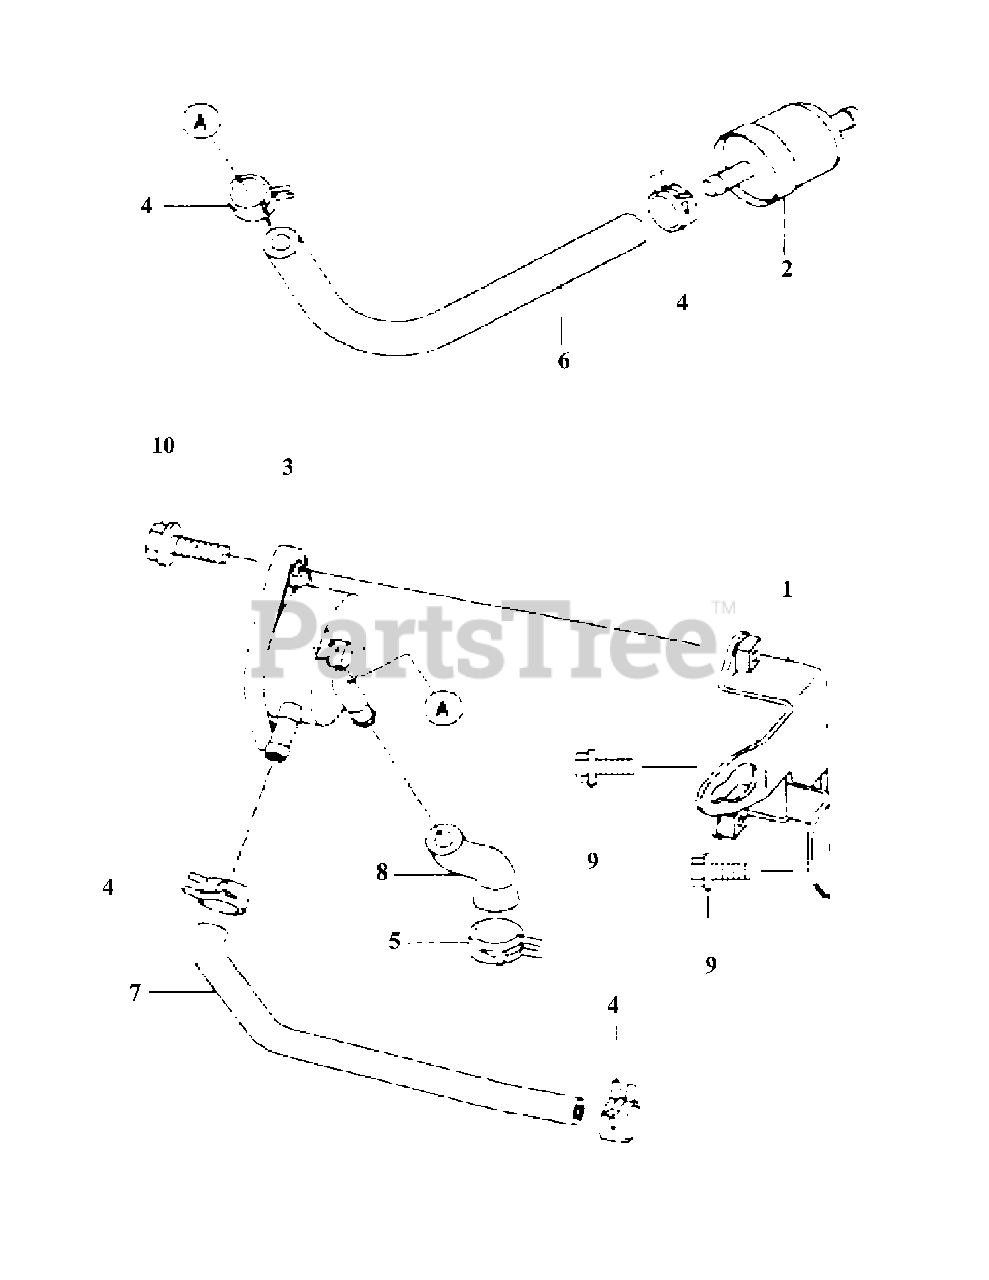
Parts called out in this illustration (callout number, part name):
2	Filter-Fuel
3	Pump-Fuel
4	Clamp
6	Tube 6.35x12.7x160
